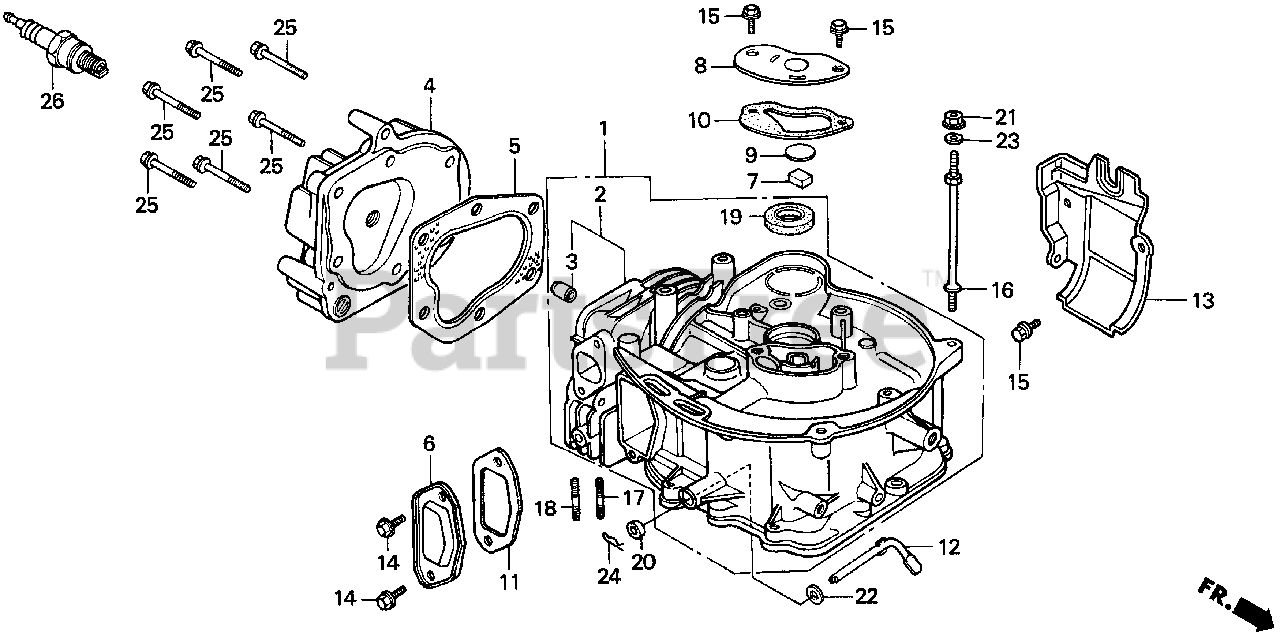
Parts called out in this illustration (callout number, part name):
1	CYLINDER ASSY.
2	CYLINDER
3	GUIDE, VALVE (OS)
4	CYLINDER HEAD
5	GASKET, CYLINDER HEAD
6	COVER, TAPPET ROOM
7	FILTER, BREATHER
8	CAP, BREATHER CHAMBER
9	VALVE, BREATHER
10	GASKET, BREATHER CAP
11	GASKET, TAPPET COVER
12	SHAFT, GOVERNOR ARM
14	BOLT, FLANGE (5X10)
15	BOLT, FLANGE (6X12) (CT200)
16	BOLT, SPECIAL STUD
17	BOLT, STUD (6X30)
18	BOLT, STUD (6X25)
19	OIL SEAL (17X30X6) (NOK)
21	NUT, FLANGE (5MM)
22	WASHER, PLAIN (5MM)
23	WASHER, PLAIN (5MM)
24	PIN, LOCK (8MM)
25	BOLT, FLANGE (6X35)
26	SPARK PLUG (BMR4A) (NGK)
